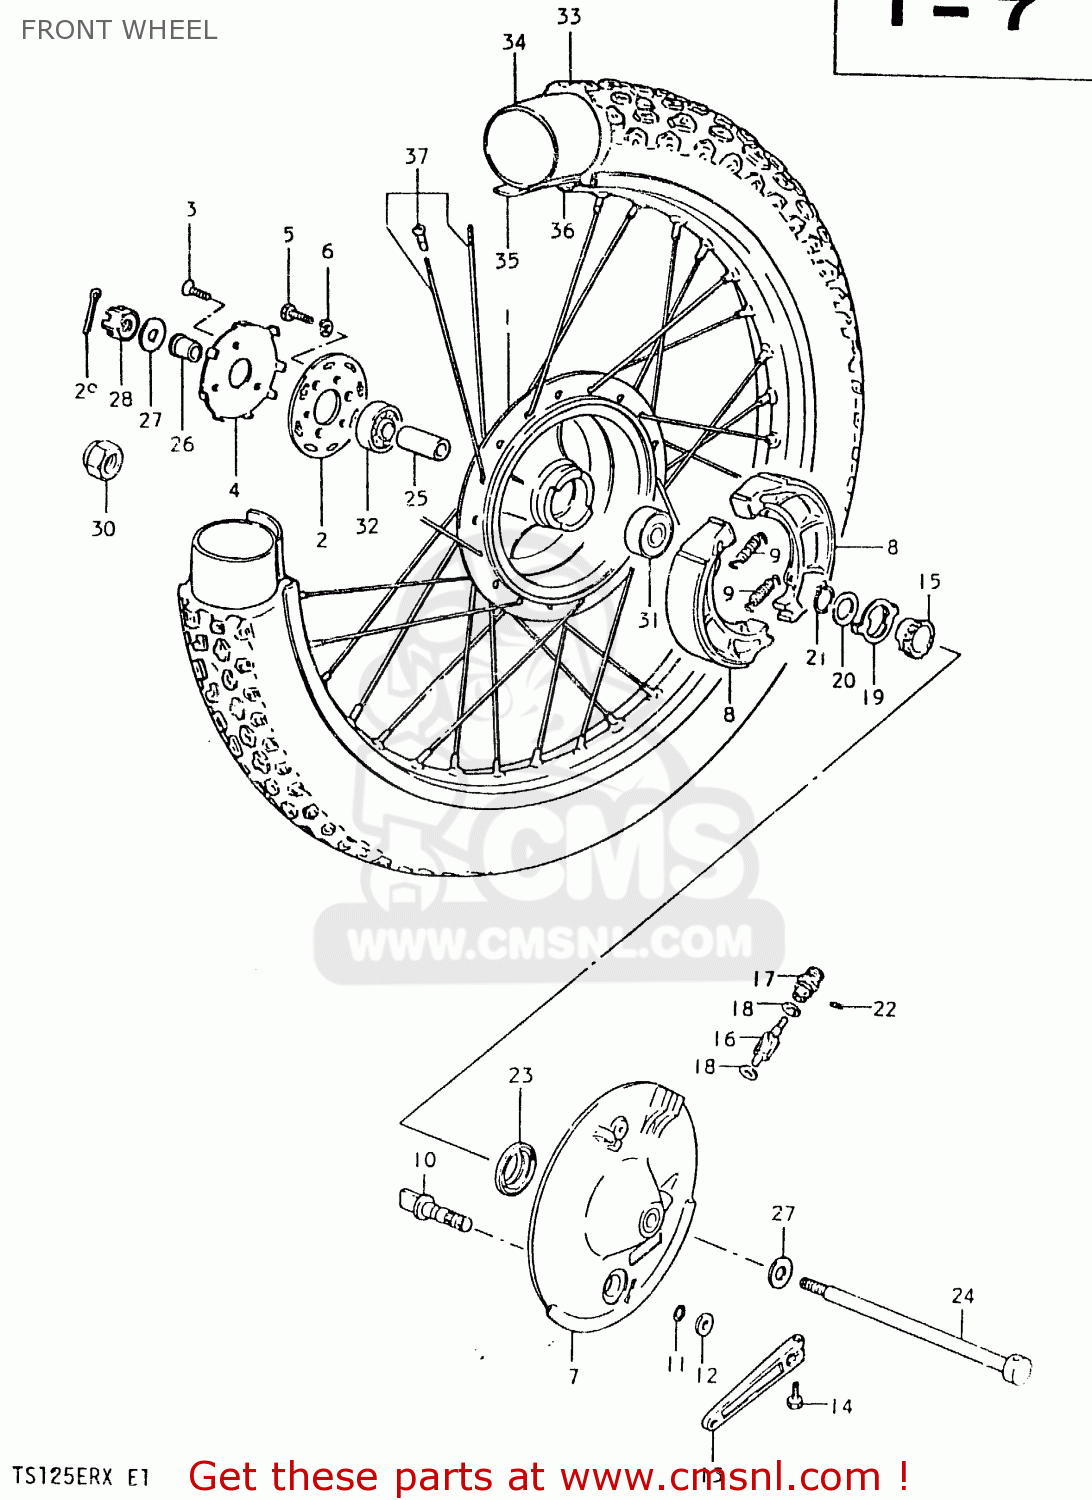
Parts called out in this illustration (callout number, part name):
1	HUB,FR WHEEL
2	FLANGE,FR HUB,R
3	SCREW
4	RETAINER,FR HUB BEARING,R
5	BOLT, UPPER
6	LOCK WASHER
7	PANEL,FRONT HUB
8	SHOE,BRAKE
9	SPRING(L:34)
10	CAM,FRONT BRAKE
11	O-RING (D:2.4 ID:13.8)
12	WASHER (14.5X22X1.6)
13	LEVER,FRONT BRAKE CAM
14	BOLT
15	GEAR,SPEEDOMETER
16	PINION,SPEEDOMETER
17	BUSH,METER GEAR OUTER
18	WASHER (5.1X9X0.4)
19	DRIVER,SPEEDOMETER GEAR
20	WASHER(18.5X24X1)
21	CIRCLIP
22	SCREW
23	OIL SEAL (43X58X7)
24	AXLE,FRONT
25	SPACER (12.6X19X52)
26	SPACER,FR AXLE,R
27	WASHER
28	NUT 12MM
29	COTTER PIN
30	NUT
31	BEARING
32	BEARING, RH
33	TIRE,FR
34	TUBE
35	PROTECTOR,WHEEL,INNER
36	RIM,FR WHEEL(1.60X21)
37	SPOKE SET,FR
